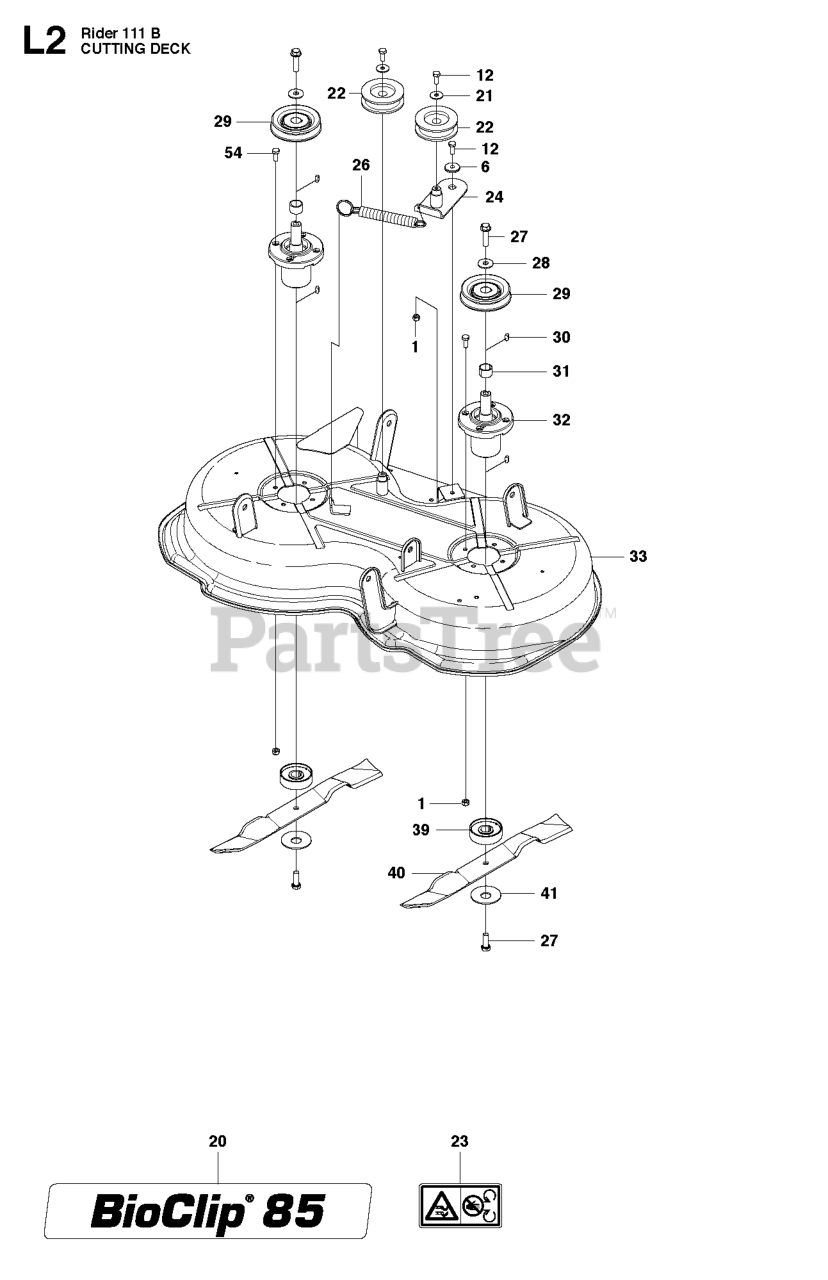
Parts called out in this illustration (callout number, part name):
1	LOCKNUT M8
6	WASHER
22	PULLEY
32	BEARING HOUSING ASSY
